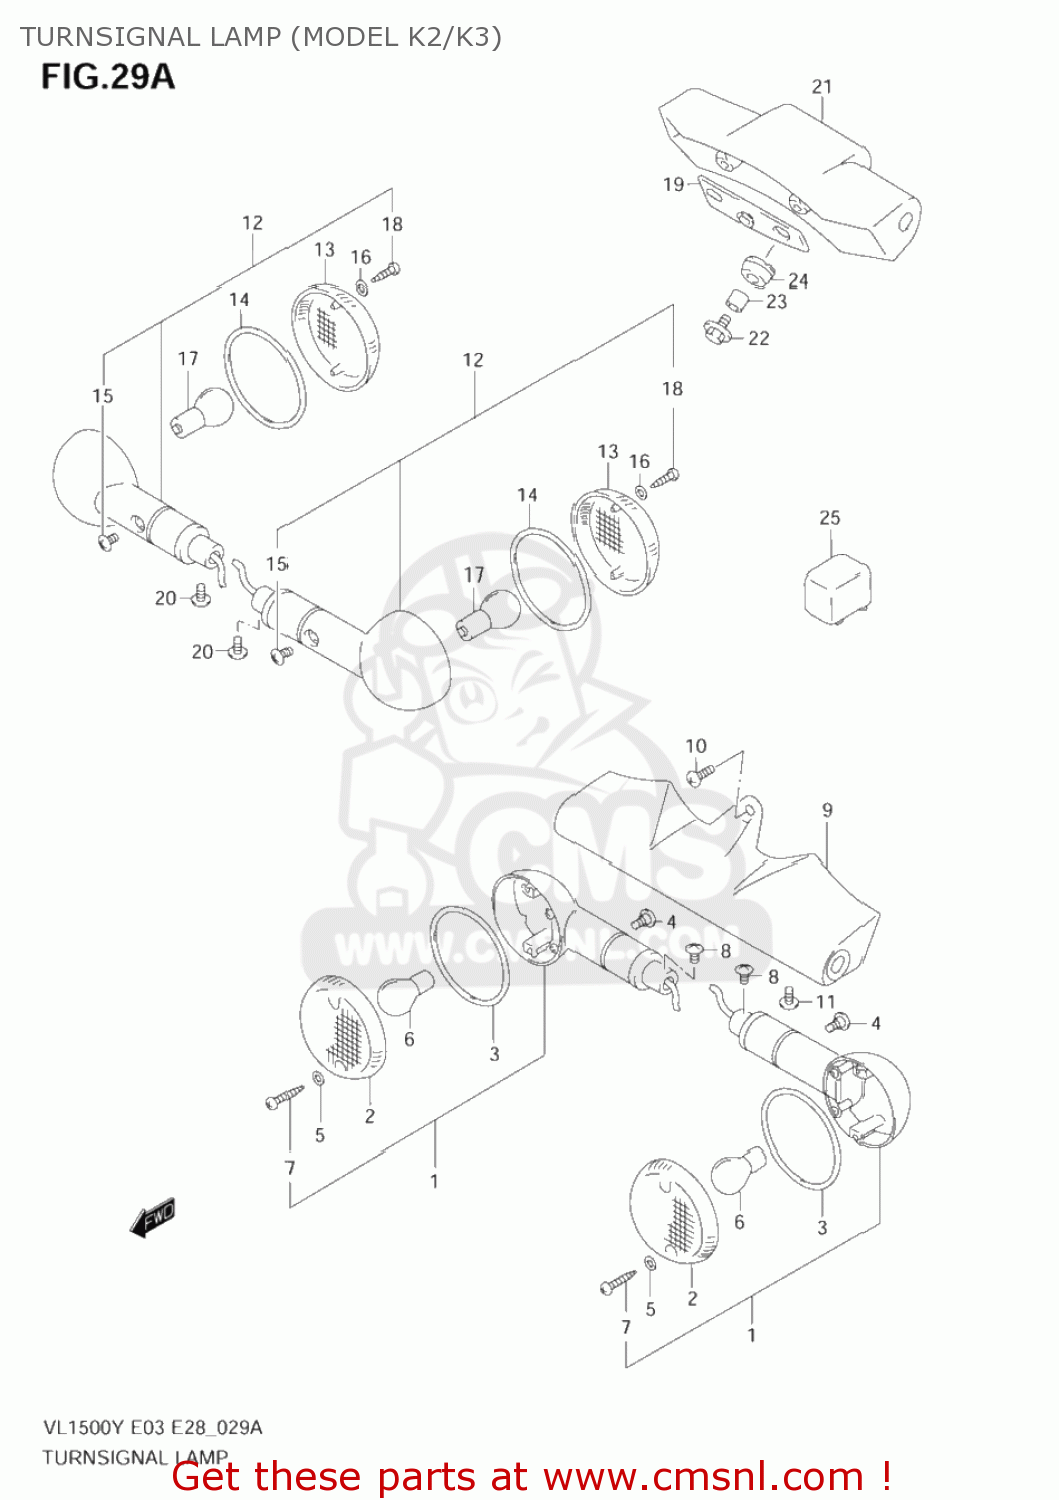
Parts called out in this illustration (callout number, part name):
1	LAMP ASSY,FR TURN SIGNAL,R
2	LENS
3	GASKET (NAS)
4	SCREW
5	GASKET (NAS)
6	BULB(12V21/5W)
7	SCREW
8	SCREW
9	STAY,FR TURNSIGNAL
10	SCREW(6X12)
11	SCREW(8X16)
12	LAMP ASSY,RR TURNSIGNAL,R
13	LENS
14	GASKET (NAS)
15	SCREW
16	GASKET (NAS)
17	BULB(12V21W)
18	SCREW
19	CUSHION,RR TURN STAY
20	SCREW
21	STAY,RR TURNSIGNAL
22	BOLT(6X20)
23	SPACER(6.5X10X10)
24	CUSHION
25	RELAY ASSY,TURNSIGNAL LAMP
